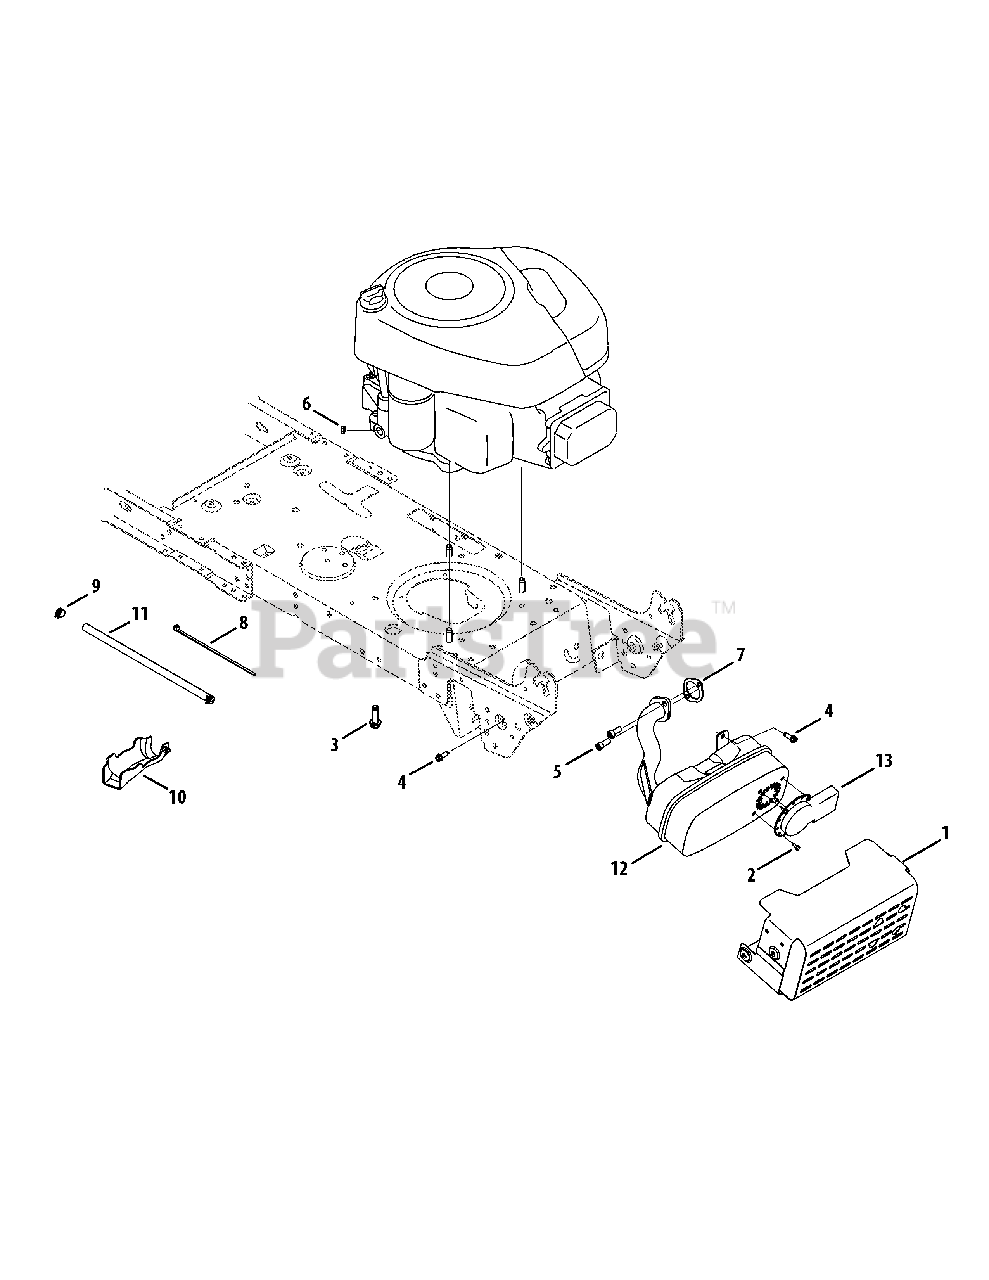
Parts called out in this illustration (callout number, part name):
1	Muffler Shield Assembly
2	Screw, AB #8-18 0.500
3	Tap Screw, 3/8-16 1.000
4	Tap Screw, 1/4-20 0.750
5	Screw, Socket Head, 5/16-18 x .750
6	Sems Nut, 1/4-20
7	Exhaust Gasket
8	Cable Tie, 3/16 X .05 X 7.4
9	Hose Clamp, .490 Dia.
10	Oil Drain Sleeve
11	Low Permeation Fuel Hose, 1/4
12	Briggs Single Muffler
13	Long Muffler Deflector
